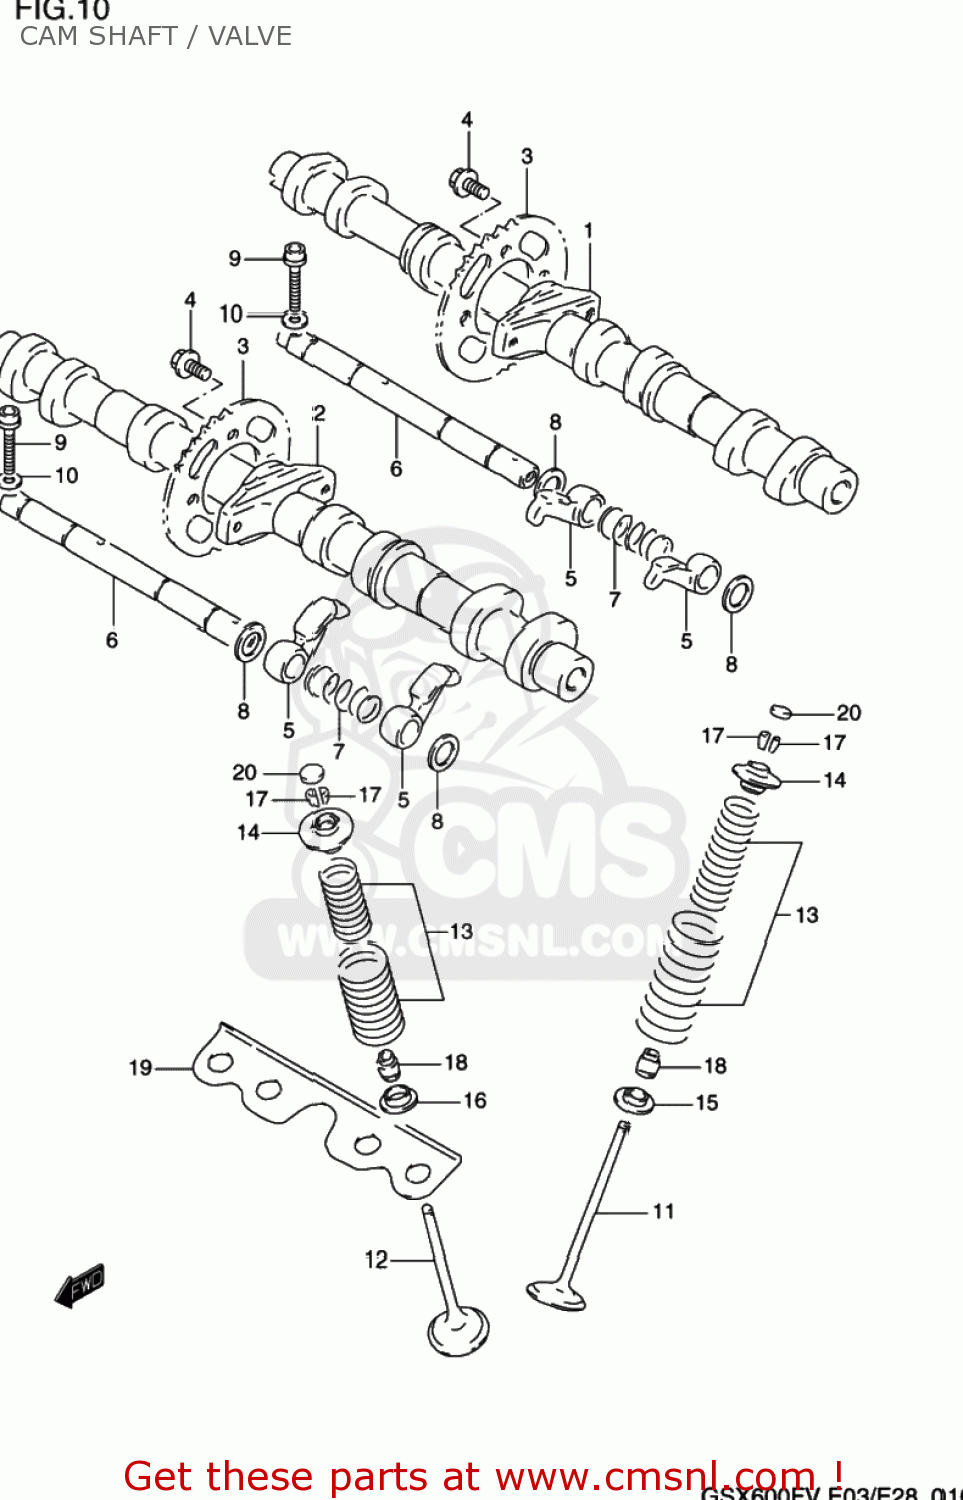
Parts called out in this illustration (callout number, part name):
1	CAMSHAFT,INTAKE
2	CAMSHAFT,EXHAUST
3	SPROCKET,CAMSHAFT
4	BOLT(7X11)
5	ARM,VALVE ROCKER
6	SHAFT,VALVE ROCKER ARM
7	SPRING
8	WASHER
9	BOLT,OIL PAN
10	WASHER
11	VALVE,INTAKE
12	VALVE,EXHAUST
13	SPRING SET,VALVE
14	RETAINER,VALVE SPRING
15	SEAT,VALVE SPRING
16	SEAT,VALVE SPRING EXH INNER
17	COTTER VALVE
18	SEAL,OIL(5X10X9.7)
19	PLATE,VALVE SEAT
20	SHIM,TAPPET(T:2.3)
21	SHIM SET,TAPPET
22	CASE,TAPPET SHIM
